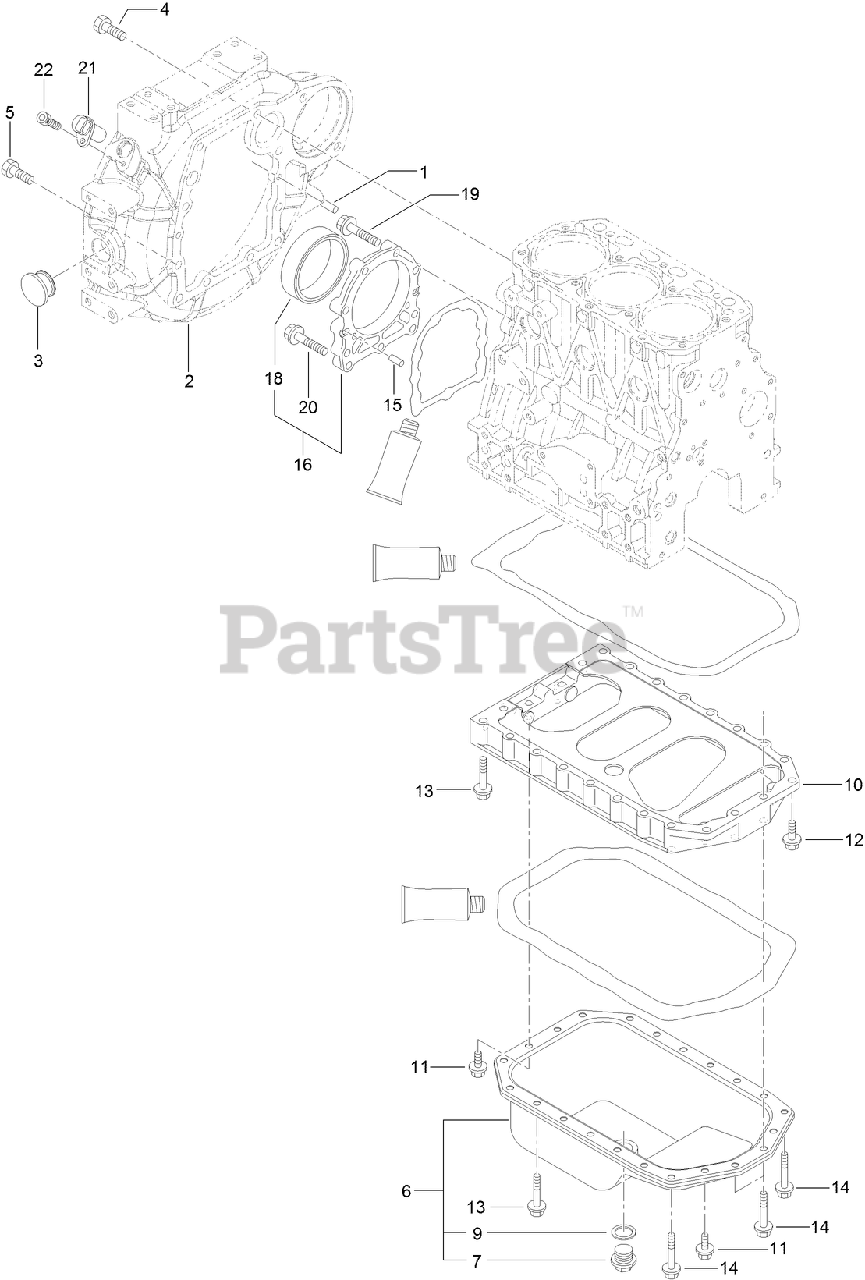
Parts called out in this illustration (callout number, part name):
2	HOUSING-FLYWHEEL
6	OIL PAN ASM
7	PLUG-DRAIN
9	WASHER-SEAL
10	SPACER
11	BOLT
16	CASE ASM
18	SEAL-OIL
21	SENSOR-REV, FLYWHEEL
